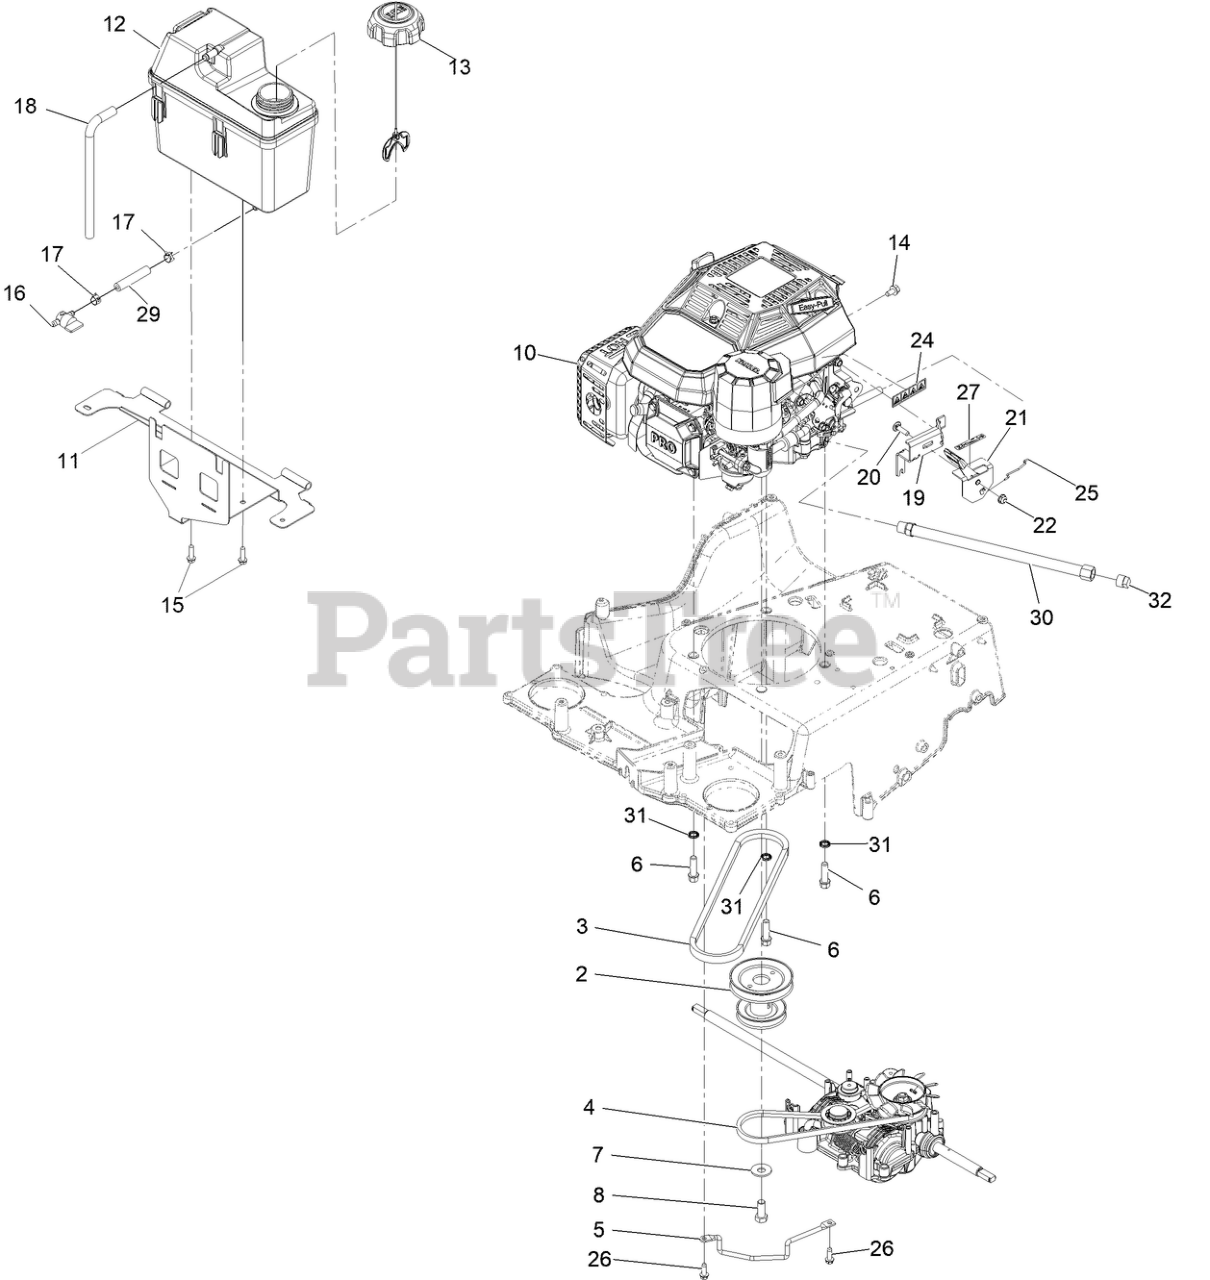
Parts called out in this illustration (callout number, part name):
2	Pulley-Engine
5	ROD-GUIDE, BELT
6	SCREW-TAPTITE
7	WASHER-BELLEVILLE
8	SCREW-HH
10	Engine-Kohler
11	TANK MOUNT ASM
12	TANK-FUEL
13	CAP-FUEL
14	SCREW-HWH
15	SCREW-HWH
16	VALVE-FUEL
17	CLAMP-HOSE
18	HOSE-VENT, CANISTER
19	BRACKET-THROTTLE
20	SCREW-CARR
21	CONTROL-THROTTLE
24	DECAL-WARNING, ENGINE
25	Wire-Link
26	SCREW-HWHTF
27	DECAL-THROTTLE, CHOKE
29	HOSE-FUEL
30	HOSE-DRAIN, OIL
31	WASHER-LOCK
32	PLUG-PIPE, SQH
